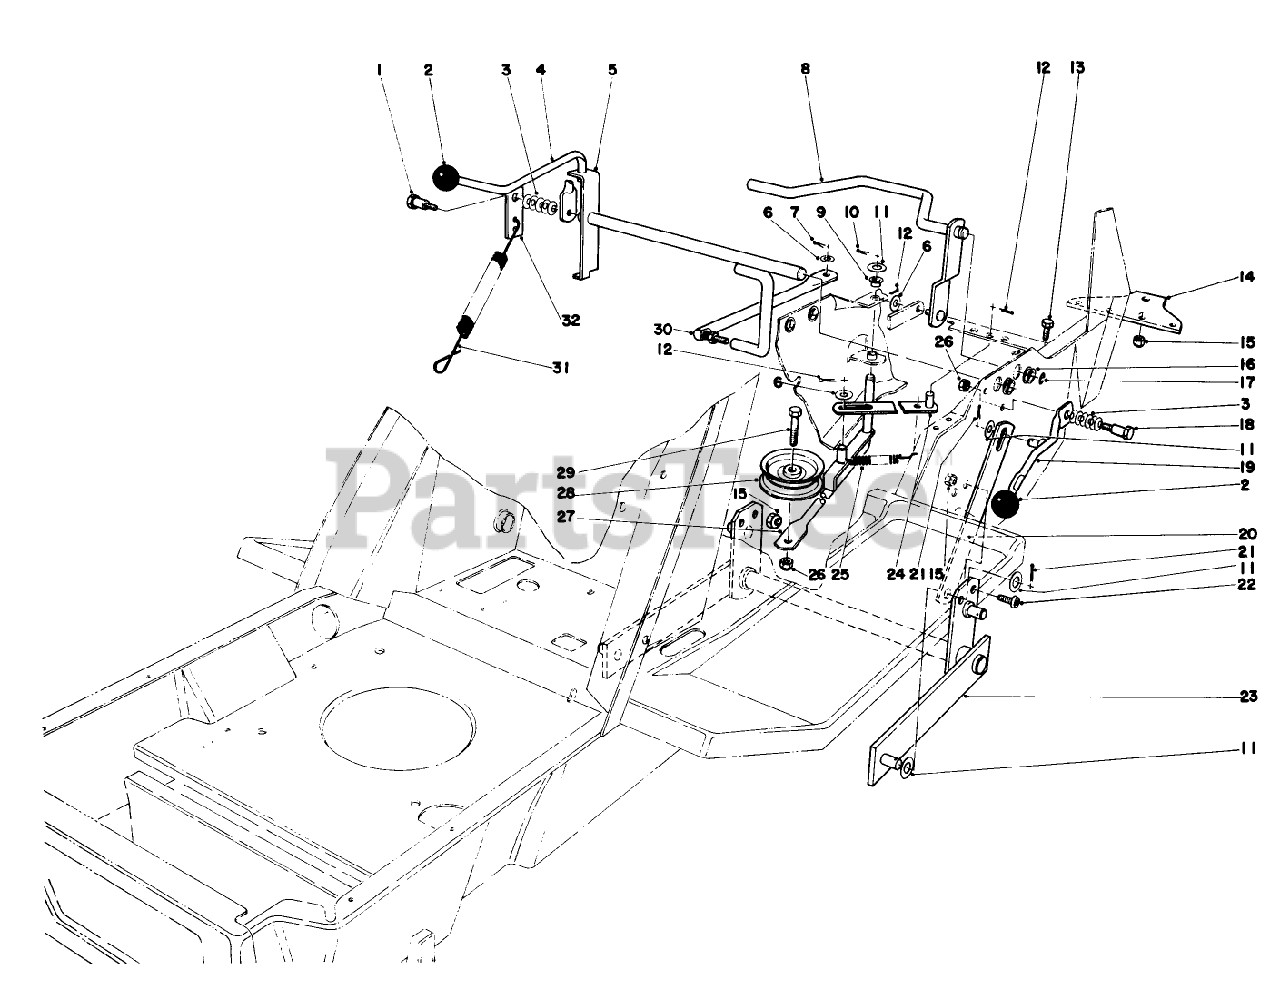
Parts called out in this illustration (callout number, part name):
1	BOLT-SHOULDER
3	WASHER-BELLEVILLE
6	WASHER-PLAIN
7	PIN-COTTER
9	BUSHING-NYLINER
10	PIN-COTTER
11	WASHER-FLAT
12	PIN-COTTER
13	SCREW-HHF
15	NUT-LOCK, CONE
17	E-RING
18	SHOULDER BOLT
21	PIN-COTTER
22	SCREW-HSBH
26	NUT-LOCK, CONE
27	IDLER ARM WA *BO
29	SCREW-HH
30	SHIFT ARM *BO
